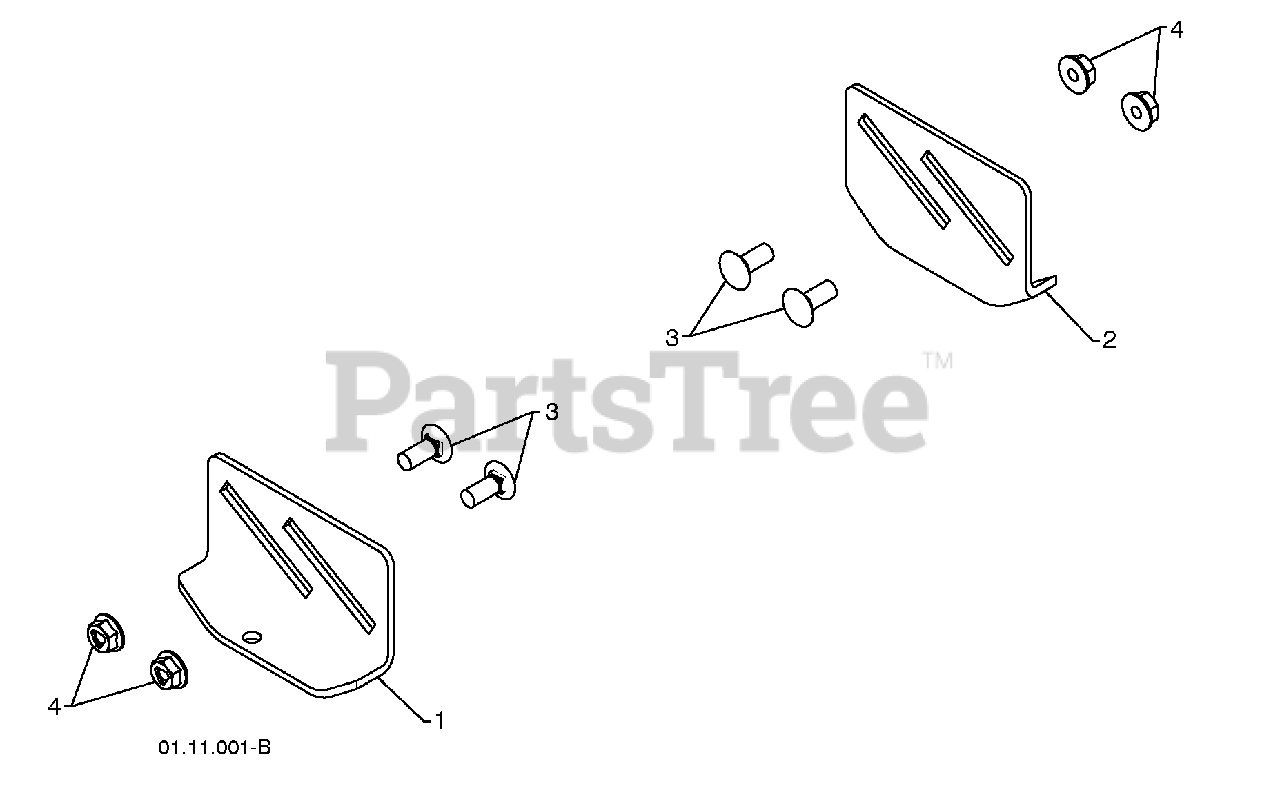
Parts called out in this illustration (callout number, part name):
1	SKID PLATE LH
2	SKID PLATE RH
3	CARRIAGE BOLT 5/16-18 X .75
4	NUT 5/16-18
